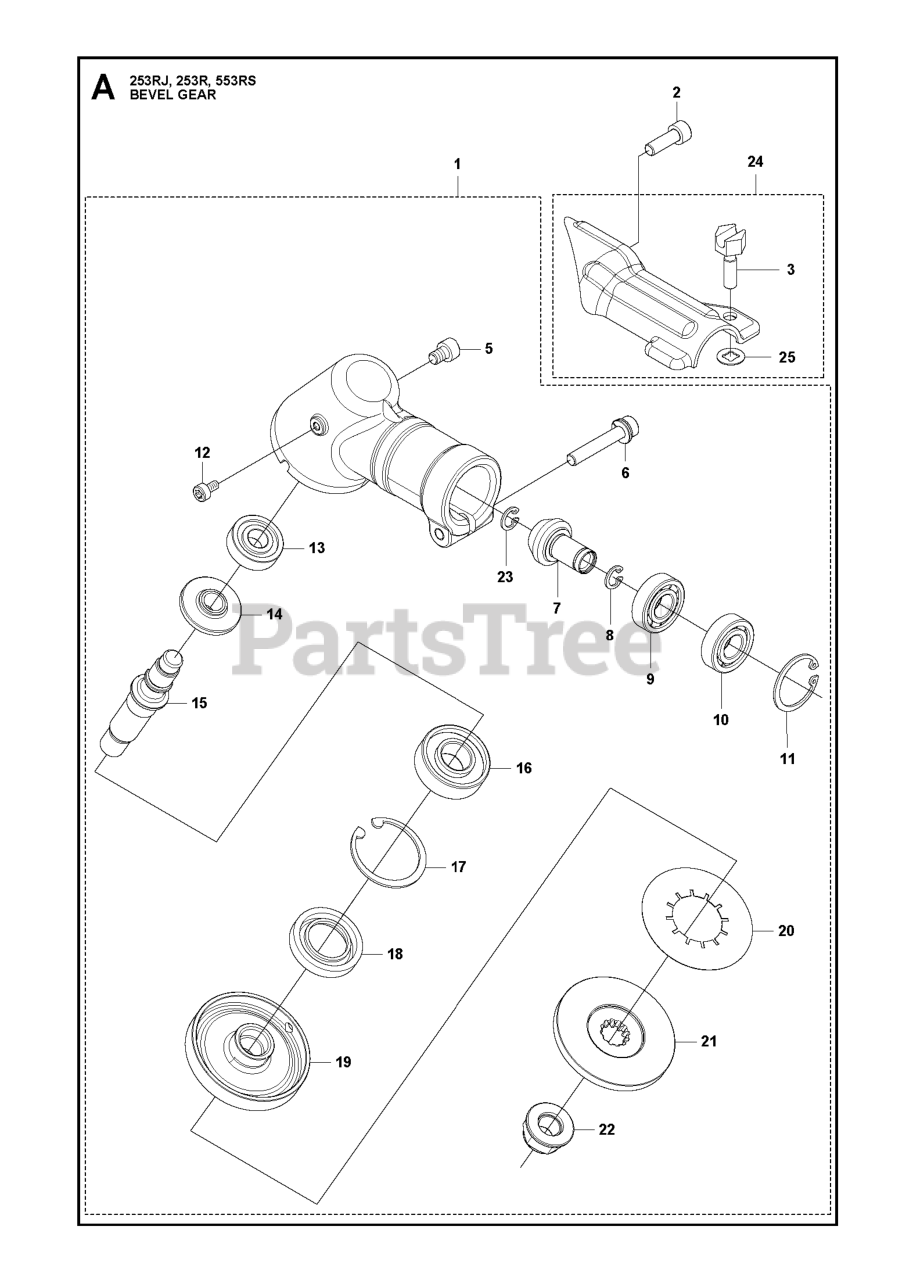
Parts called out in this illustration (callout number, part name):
5	BOLT,TORX M6X8
10	BEARING,12MM ID,28MM OD, 8MM W
15	SHAFT,GEAR
16	BEARING 0600406202
24	BRACKET ASSY
25	LOCK WASHER
